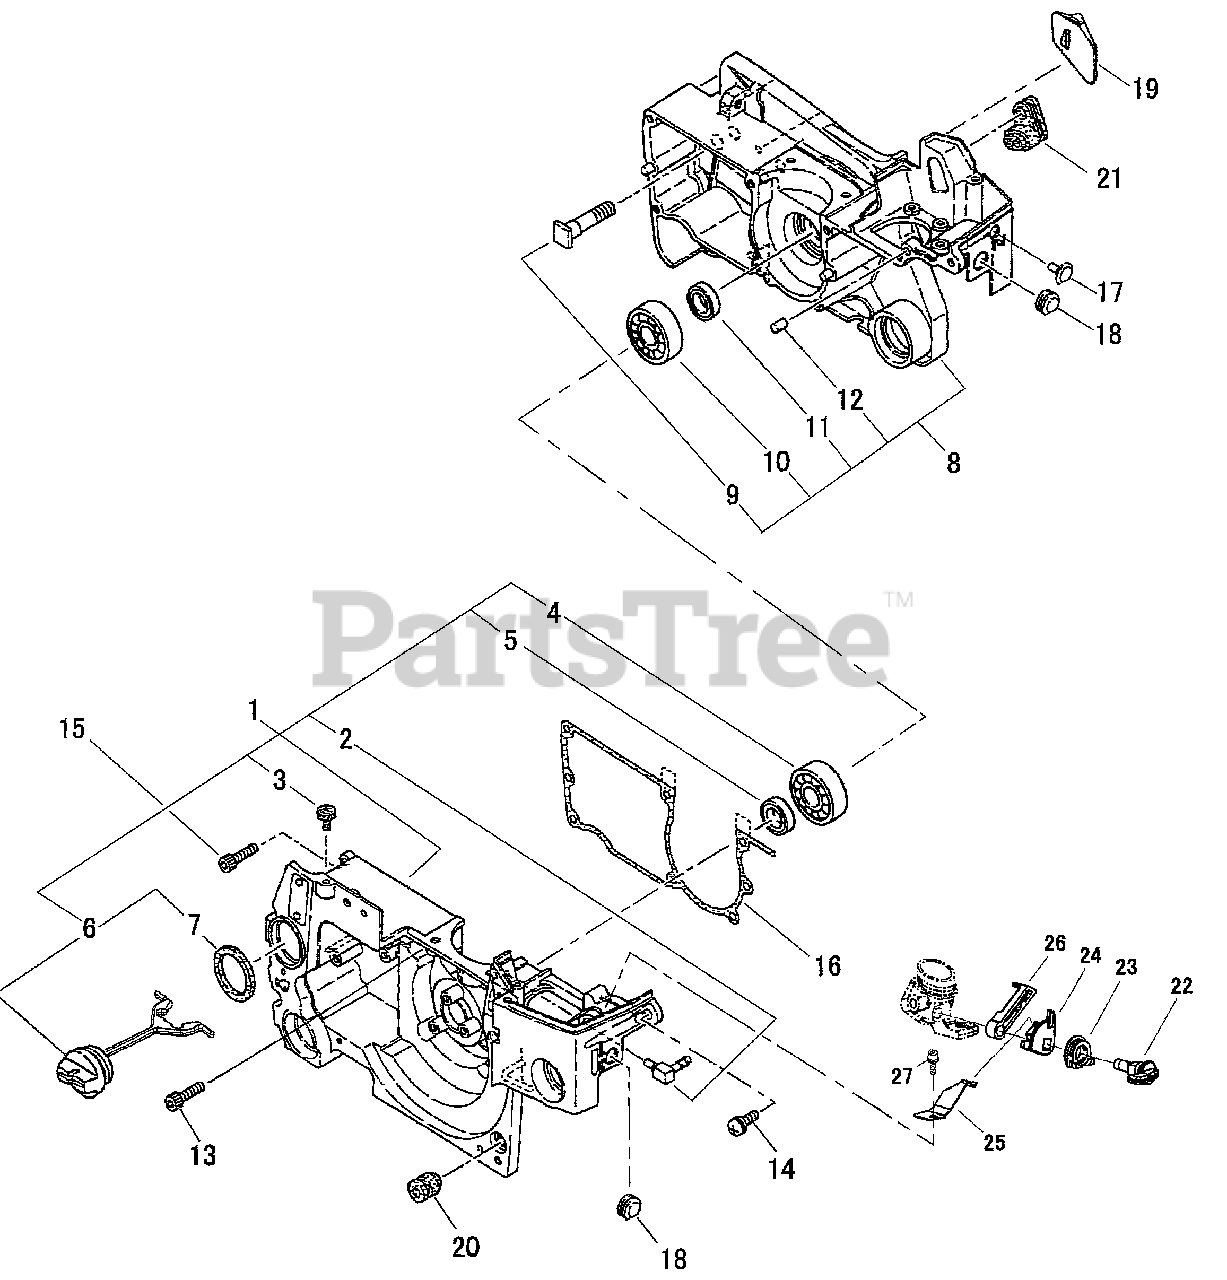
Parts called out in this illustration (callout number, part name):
1	CRANKCASE ASSY - LEFT
2	CONNECTOR, PIPE
3	VALVE, OIL
4	BEARING, BALL - 6201C3
5	SEAL, OIL
6	CAP ASSY
7	GASKET
8	CRANKCASE ASSY - RIGHT
9	STUD, GUIDE BAR
10	BEARING, BALL - 6201C3
11	SEAL, OIL
12	PIN - LOCATING
13	BOLT - 5X30
14	SCREW
15	BOLT - 5X18
16	GASKET, CRANKCASE
17	CLAMP - A
18	PLUG
19	STOPPER
20	SUPPORT
22	SWITCH, IGNITION
25	PLATE, SPRING
26	CHOKE
27	SCREW - 4X10
